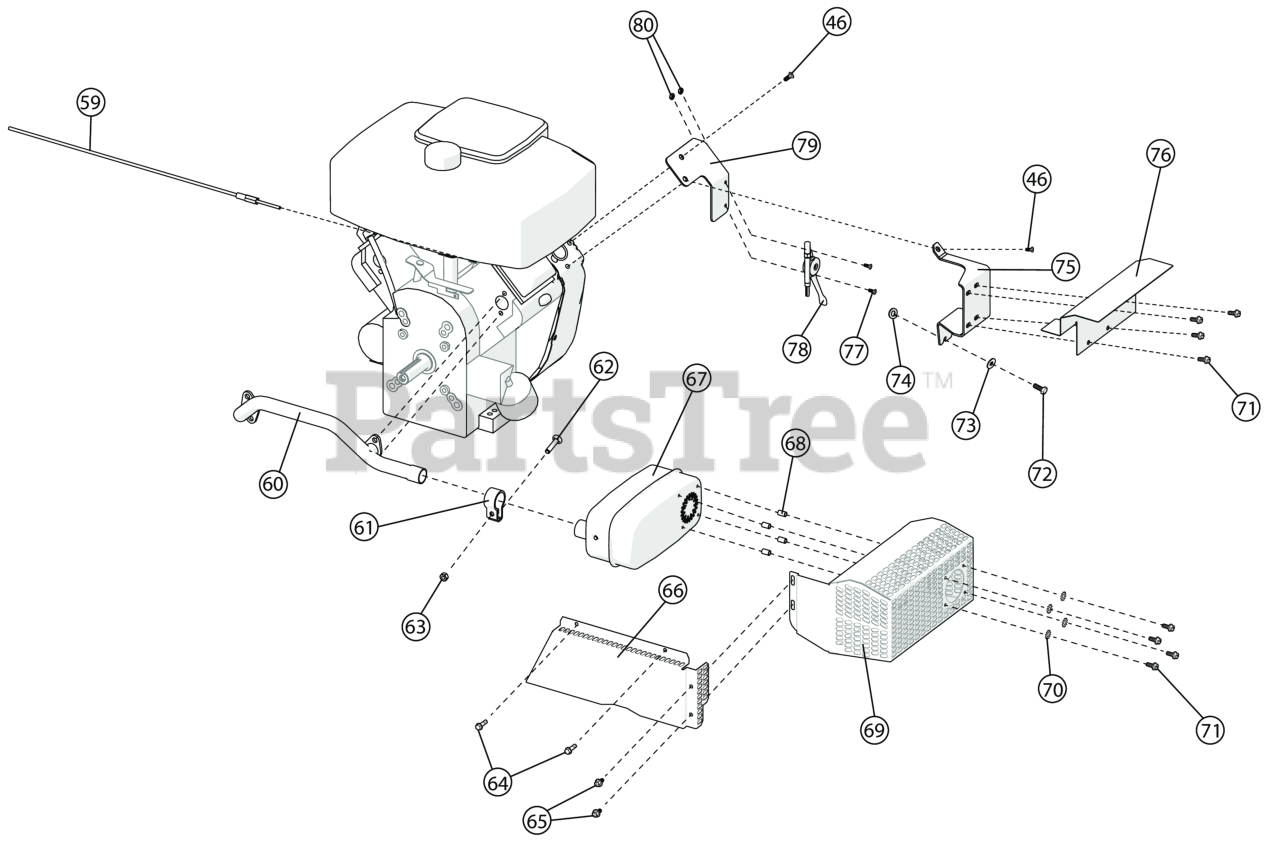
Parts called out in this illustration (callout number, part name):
46	REF
59	CABLE THROTTLE DL18
60	REF
61	MUFFLER CLAMP VN
62	BOLT CARRIAGE 5/16"-18 X 1 3/4" ZP
63	NUT 5/16"-18 FIN HEX Z/P
64	SCREW SM 1/4" X 3/4" DRILL PT.
65	BOLT 1/4-20 X 1/2 SER FLANGE
66	GUARD MANIFOLD DL18
67	MUFFLER 18 HP VN
68	SPACER CONTROL LIFT
69	GUARD, MUFFLER DL18 SW
70	WASHER LOCK 1/4" EXTERNAL TOOTH
71	SCREW SELF TAP 1/4"-20 X 5/8" HWH TYPE F
72	SCREWCAP M6 X 16 ZP
73	WASHER M6 FLAT Z
74	WASHER LOCK M6 ZP
75	MUFFLER MOUNT BRACKET VN
76	MUFFLER HEAT SHIELD VN
77	SCREW MACHINE FLAT HD PHIL #10-24
78	CONTROL THROTTLE BLOWER
79	BRACKET MOUNT THROTTLE CONTROL
80	NUT LOCK LT #10-24 HEX
